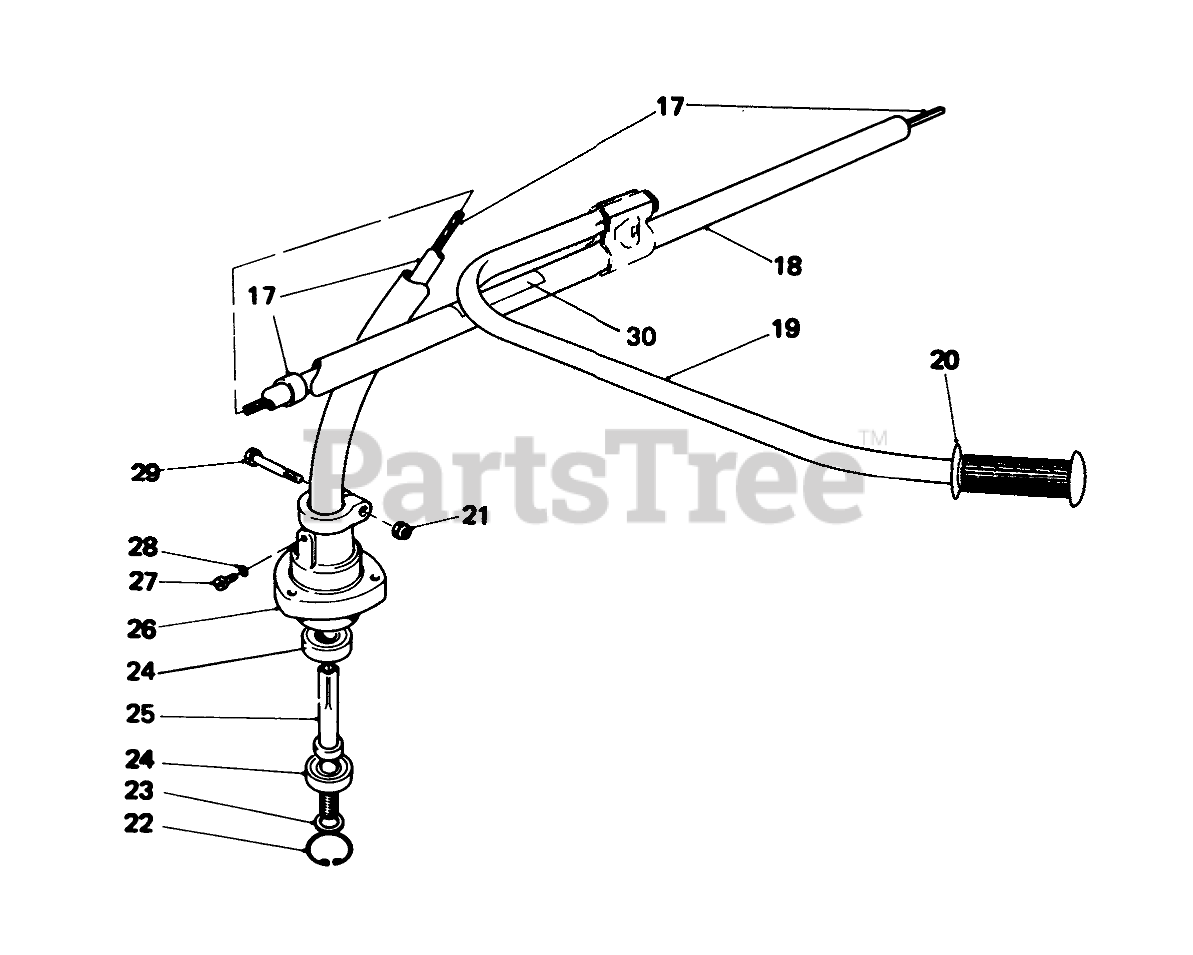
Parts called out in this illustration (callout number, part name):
17	Drive Shaft and Casing Assy.
18	Tube-Shaft Housing
19	Tube-Support Handle
20	Grip-Support Handle
21	NUT-LOCK, NI
22	RING-SNAP
23	Bearing Spacer
24	Bearing
25	POWER SHAFT
26	Bearing Case
27	Screw
28	WASHER-LOCK
29	SCREW-SHH
30	Caution Decal
